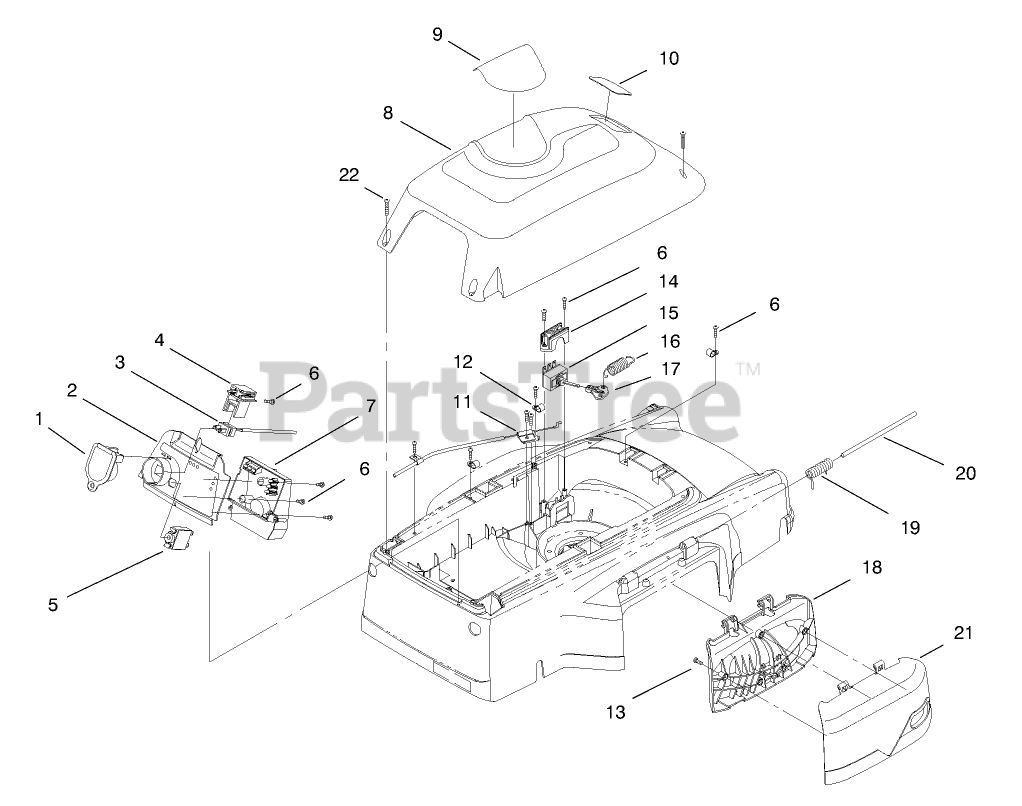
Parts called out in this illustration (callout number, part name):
4	HOUSING - PLUG
5	CIRCUIT BREAKER
6	SCREW-PPH
8	COVER ASM
11	BRACKET - CABLE
13	SCREW
17	COVER LEVER-SWITCH
20	PIN - HINGE, MULCH PLUG
22	SCREW-PPH
